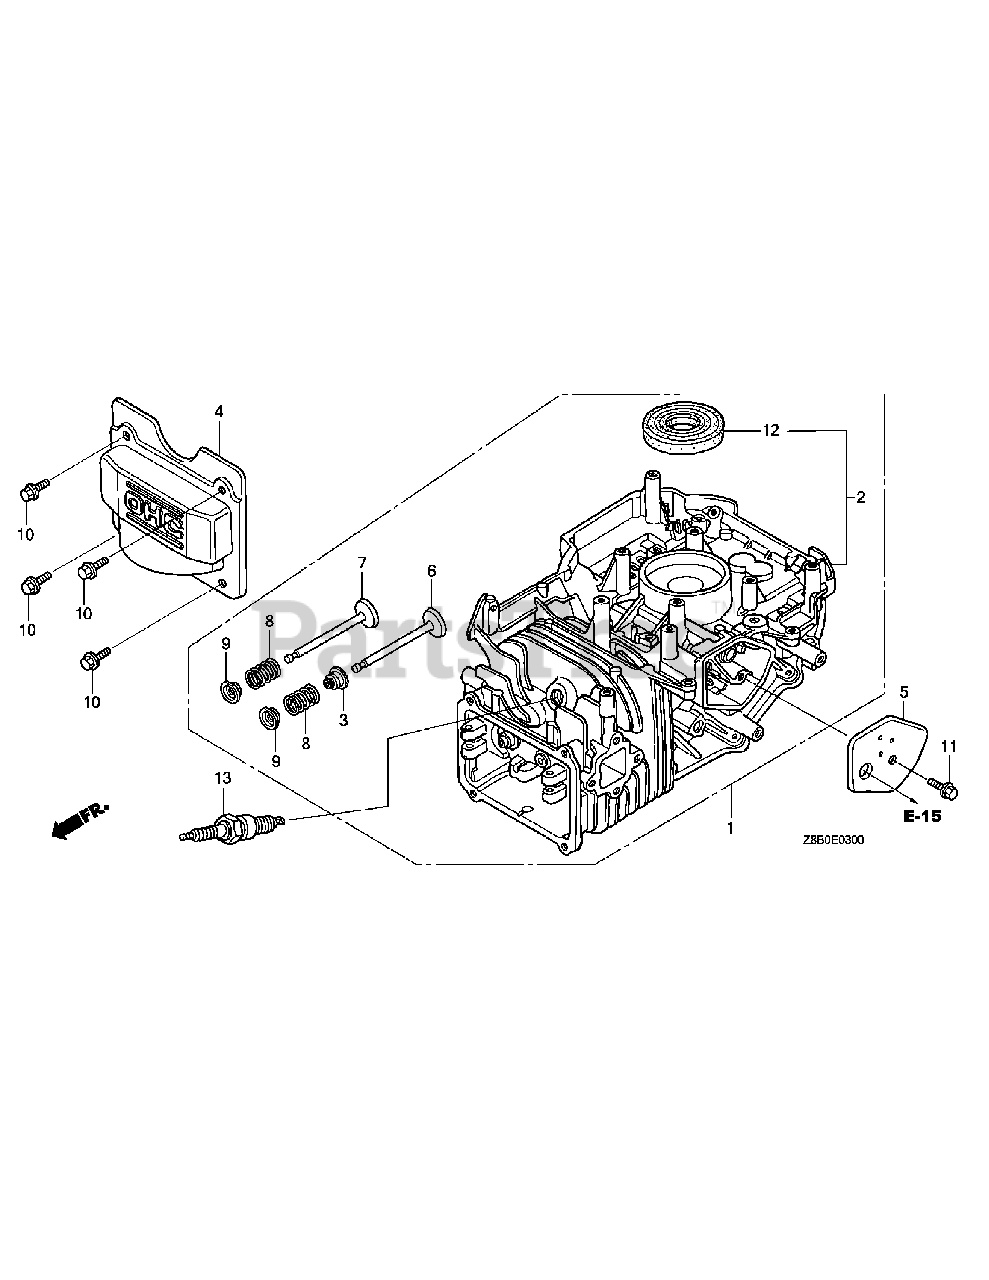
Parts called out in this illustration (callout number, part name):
1	BARREL ASSY., CYLINDER
3	SEAL, VALVE STEM
4	COVER, HEAD
5	COVER COMP., BREATHER
6	VALVE, IN.
7	VALVE, EX.
8	SPRING, VALVE
9	RETAINER, VALVE SPRING
10	BOLT, FLANGE, 6X12(CT200)
11	BOLT, FLANGE, 6X14(CT200)
12	OIL SEAL, 25.4X62X6
13	PLUG, SPARK (BPR6ES)(NGK)
